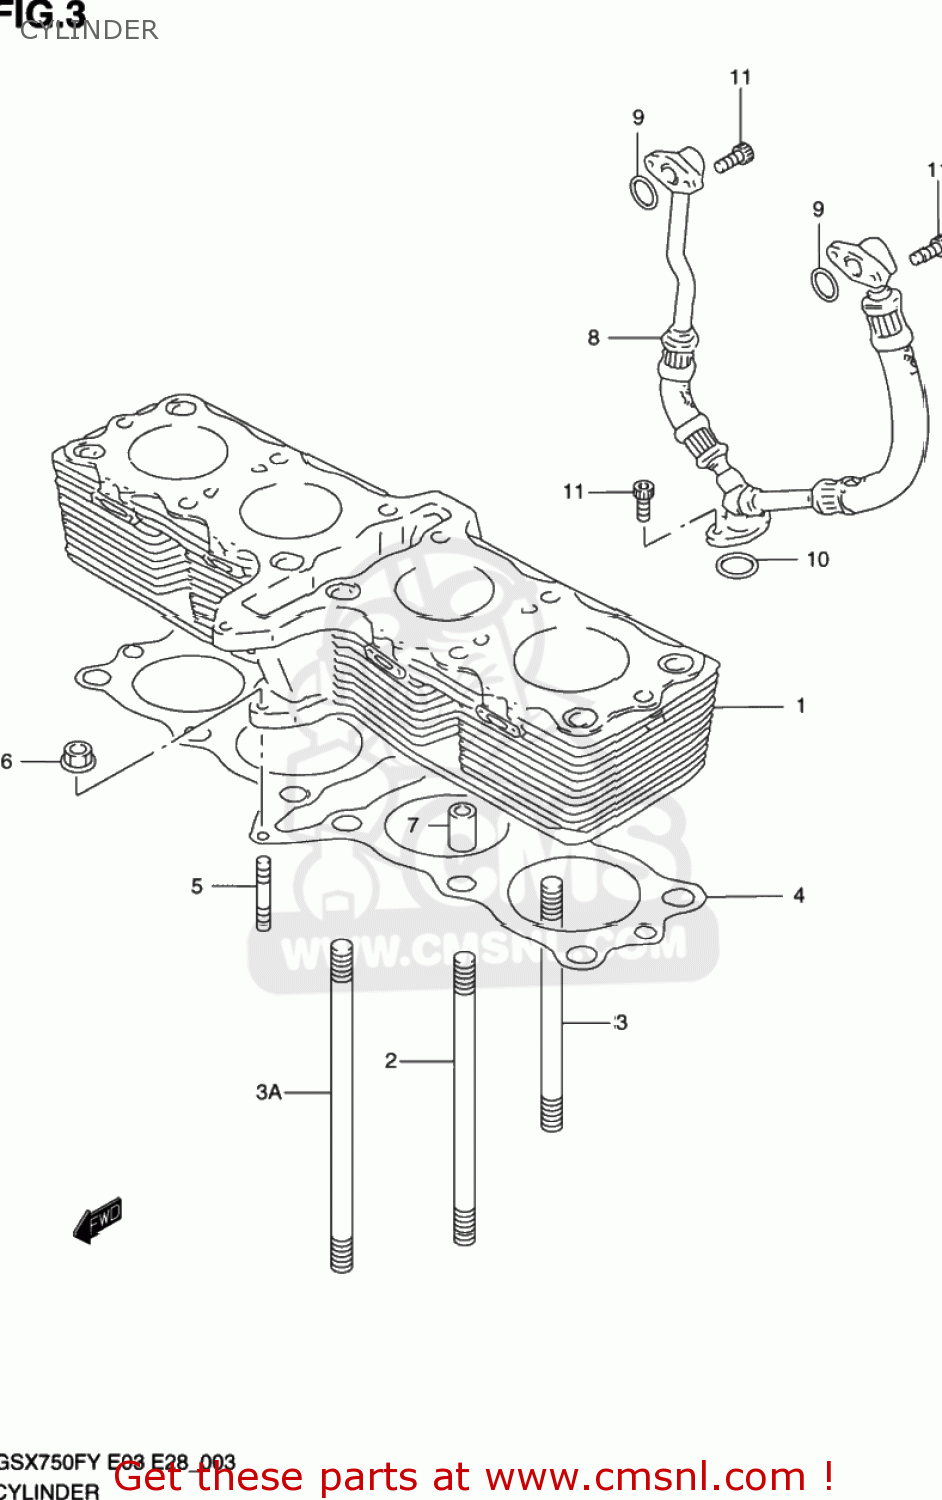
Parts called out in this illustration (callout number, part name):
1	CYLINDER
2	STUD BOLT (L:150)
3	BOLT,STUD
3A	BOLT,STUD
4	GASKET,CYLINDER (NAS)
5	STUD,M6X1X32
6	NUT
7	PIN(13X10.4X20)
8	HOSE,OIL HEAD COOLER
9	O RING(D:2.5,ID:13.8)
10	O RING(D:2.4,ID:15.8)
11	BOLT,OIL FILLE
